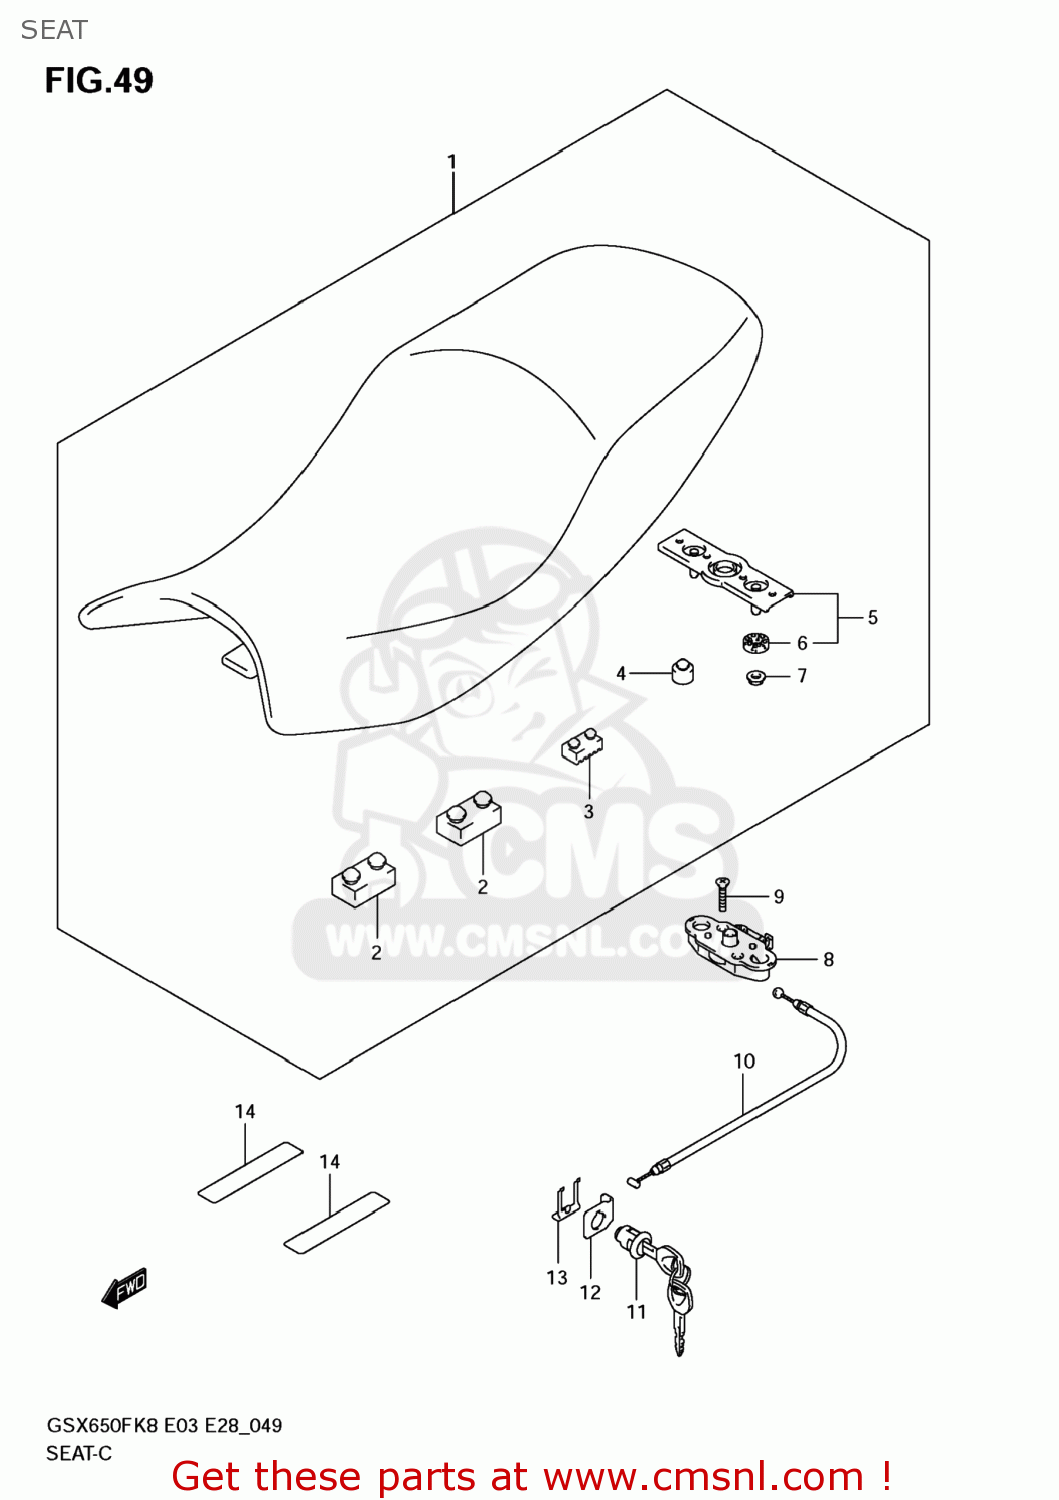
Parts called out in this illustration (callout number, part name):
1	SEAT ASSY
2	CUSHION
3	CUSHION
4	CUSHION
5	STRIKER,SEAT LOCK
6	CUSHION
7	NUT
8	BRACKET,SEAT SUPPORT
9	SCREW
10	CABLE,SEAT LOCK
11	LOCK SET,SEAT
12	GUIDE,SEAT LOCK CABLE
13	PLATE,SEAT LOCK ASSY
14	TAPE,SEAT LWR COVER
